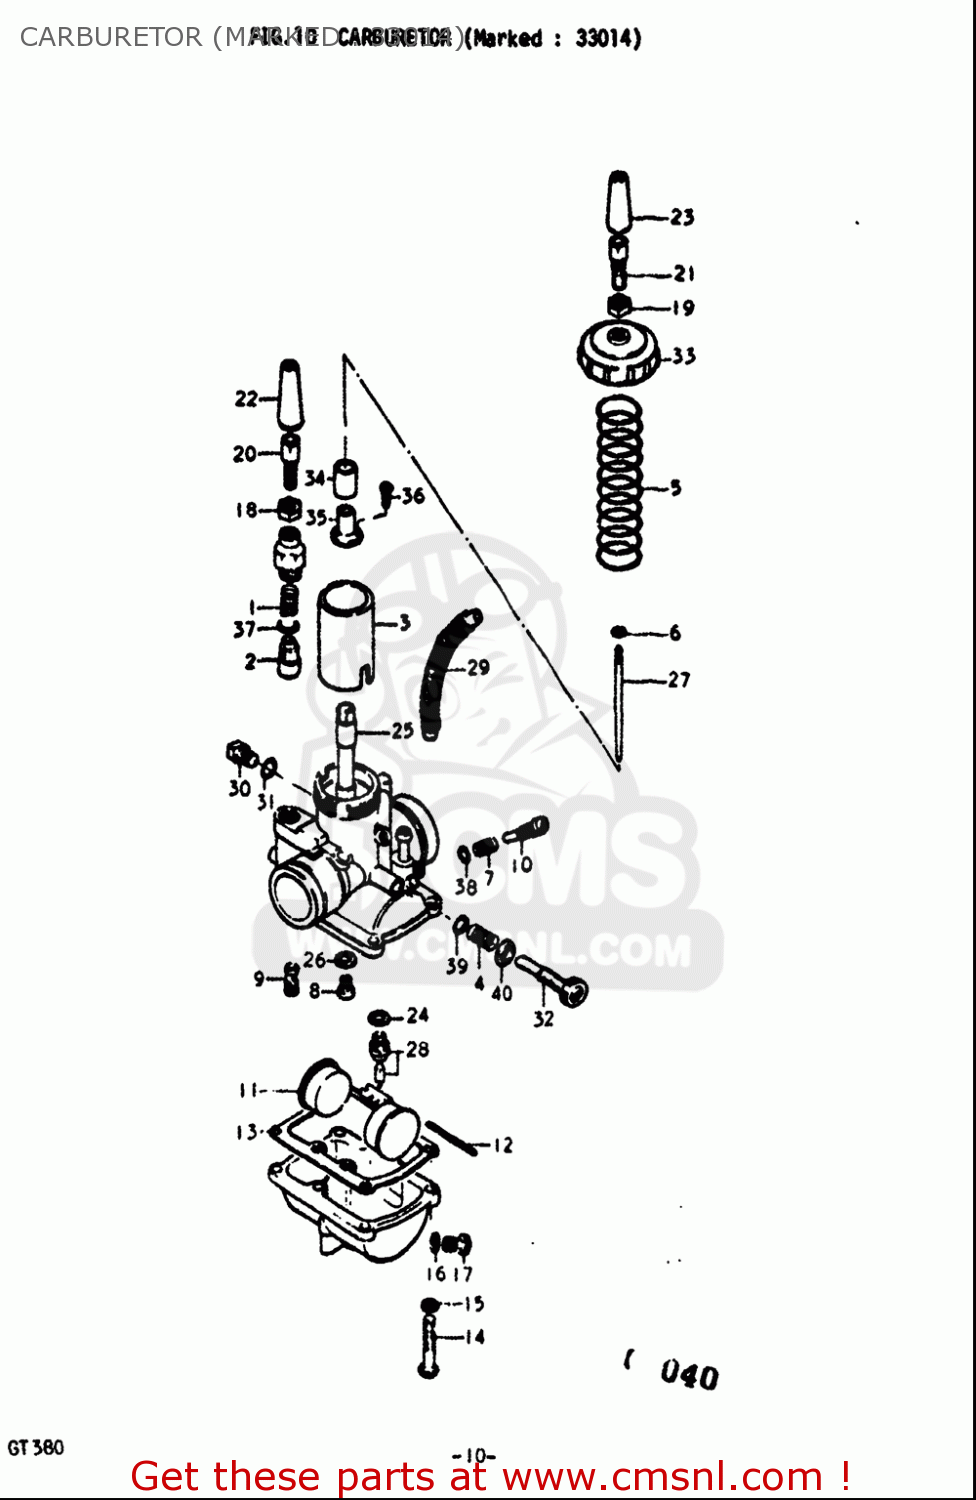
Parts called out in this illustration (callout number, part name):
1	SPRING
2	PLUNGER,STARTER
4	SPRING
6	CLIP
7	SPRING
8	JET,MAIN
9	JET,PILOT(22.5)
12	PIN,FLOAT
13	GASKET,FLOAT CAHMBER (NAS)
14	SCREW 4X16
15	WASHER,LOCK
16	GASKET,DRAIN,PLUG (NAS)
18	NUT
20	ADJUSTER,CABLE
21	ADJUSTER,CABLE
22	CAP
24	GASKET,VALVE SEAT (NAS)
26	WASHER
27	NEEDLE,JET
28	VALVE ASSY,NEEDLE
30	BOLT
31	GASKET,THRO VALVE INSPECTION (NAS)
35	CONNECTOR
36	SCREW
38	O RING
39	O RING
40	COVER
